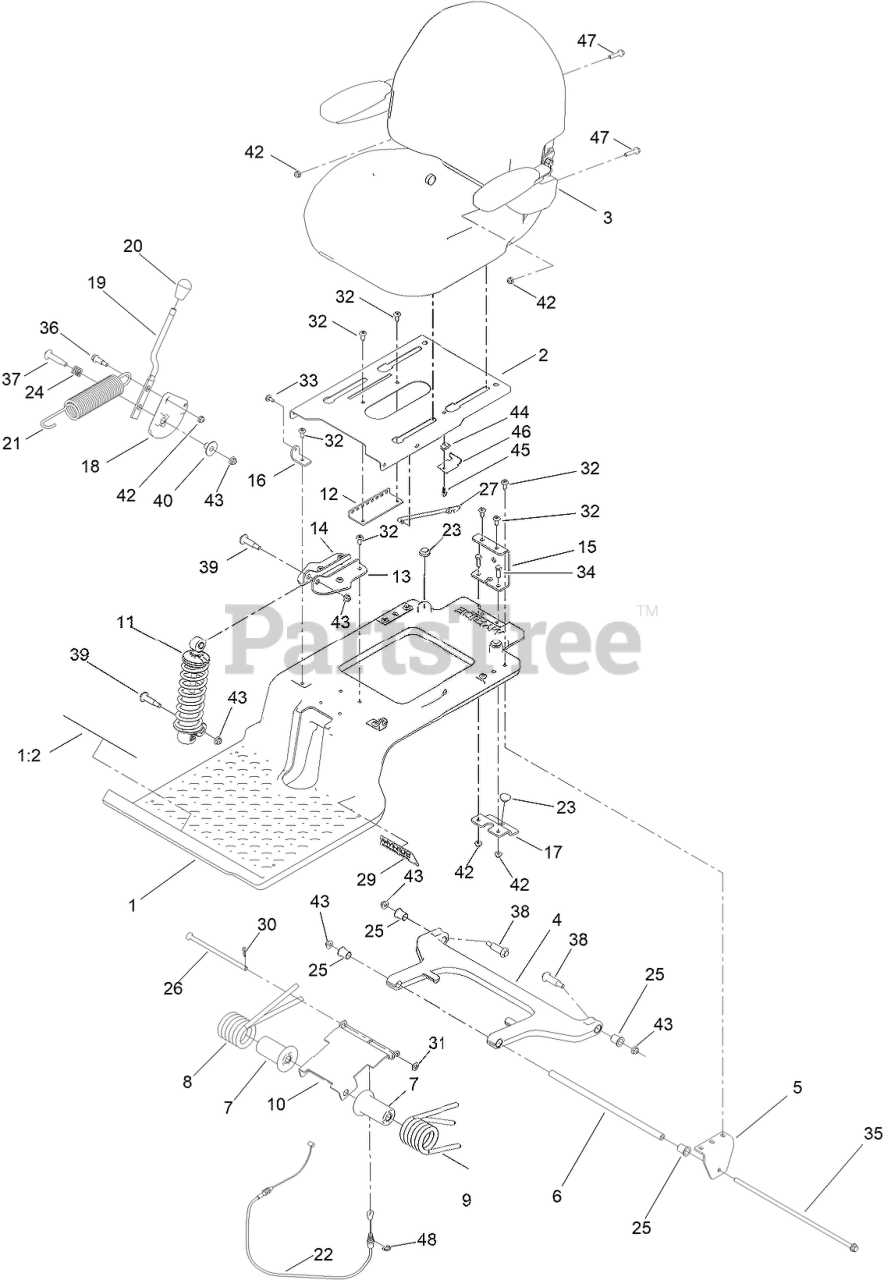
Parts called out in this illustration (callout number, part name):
1	SUBFRAME ASM
1:2	DECAL-DANGER
2	PAN-SEAT
3	SEAT ASM
4	ARM, SWING
5	BRACKET-MOUNT, SWING ARM
6	TUBE-SPACER
7	RETAINER-SPRING
8	SPRING-TORSION, RH
9	SPRING-TORSION, LH
10	PLATE-ADJUSTER
11	SHOCK/SPRING ASM
12	BRACKET-LATCH, SEAT
13	BRACKET-SHOCK MOUNT, UPPER (LH)
14	BRACKET-SHOCK MOUNT, UPPER (RH)
15	BRACKET-CABLE
16	BRACKET-SEAT
17	BRACKET LOWER
18	PULLEY - CAM
19	LEVER - ADJUSTMENT
20	KNOB-MR
21	SPRING-EXTENSION
22	CABLE-ADJUSTMENT, MYRIDE
23	BUMPER-SEAT
24	SPRING-COMPRESSION
25	BUSHING-FLANGE
26	ROD-ADJUSTMENT
27	ROD-PROP, SEAT
29	DECAL-MYRIDE
30	PIN-HAIR
31	WASHER-FLAT
33	SCREW-SHOULDER
34	SCREW-HH
35	SCREW-HHF
36	BOLT-SHOULDER, HHF
37	BOLT-SHOULDER
38	BOLT-SHOULDER
39	BOLT-SHOULDER
40	BUSHING - FLANGE
42	NUT-HF
43	NUT-HF, NI
45	SCREW-HHF
46	BRACKET-STOP, SEAT
47	SCREW-HHF
48	RING-RETAINING, EXTERNAL
